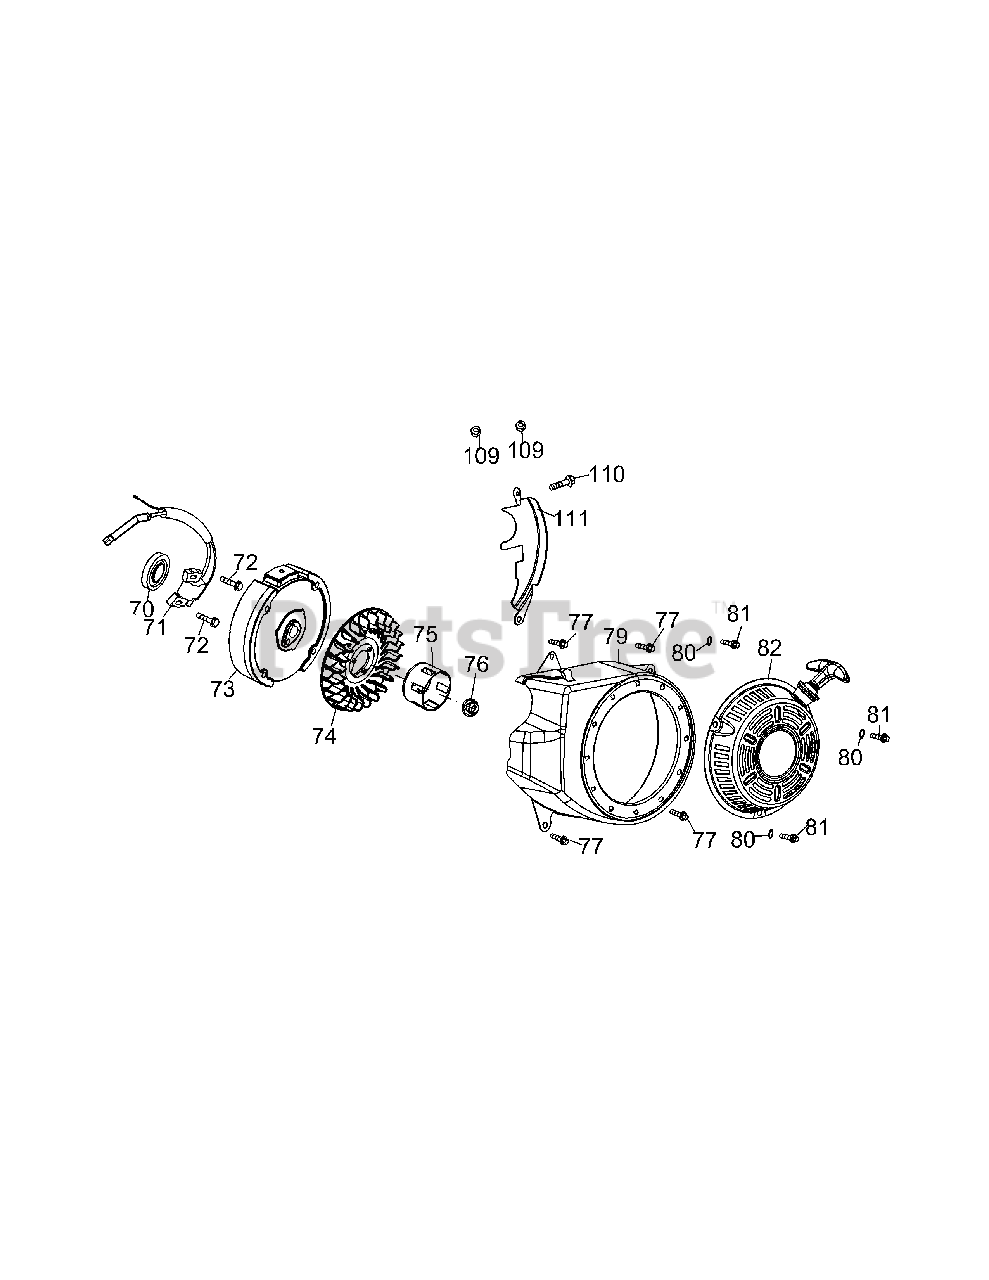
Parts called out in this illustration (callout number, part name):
70	Oil Seal 25×41.25×6
71	Ignition Coil Assembly
72	Bolt M6×25
73	Flywheel
74	Fan, Cooling
75	Pulley, Starter
76	Nut, Special, M14×1.5
77	Bolt M6×12
79	Blower Housing
80	Flat Washer
81	Bolt M6×10
82	Recoil Starter
109	Nut, M6
110	Bolt M6×20
111	Blower Housing Shield
